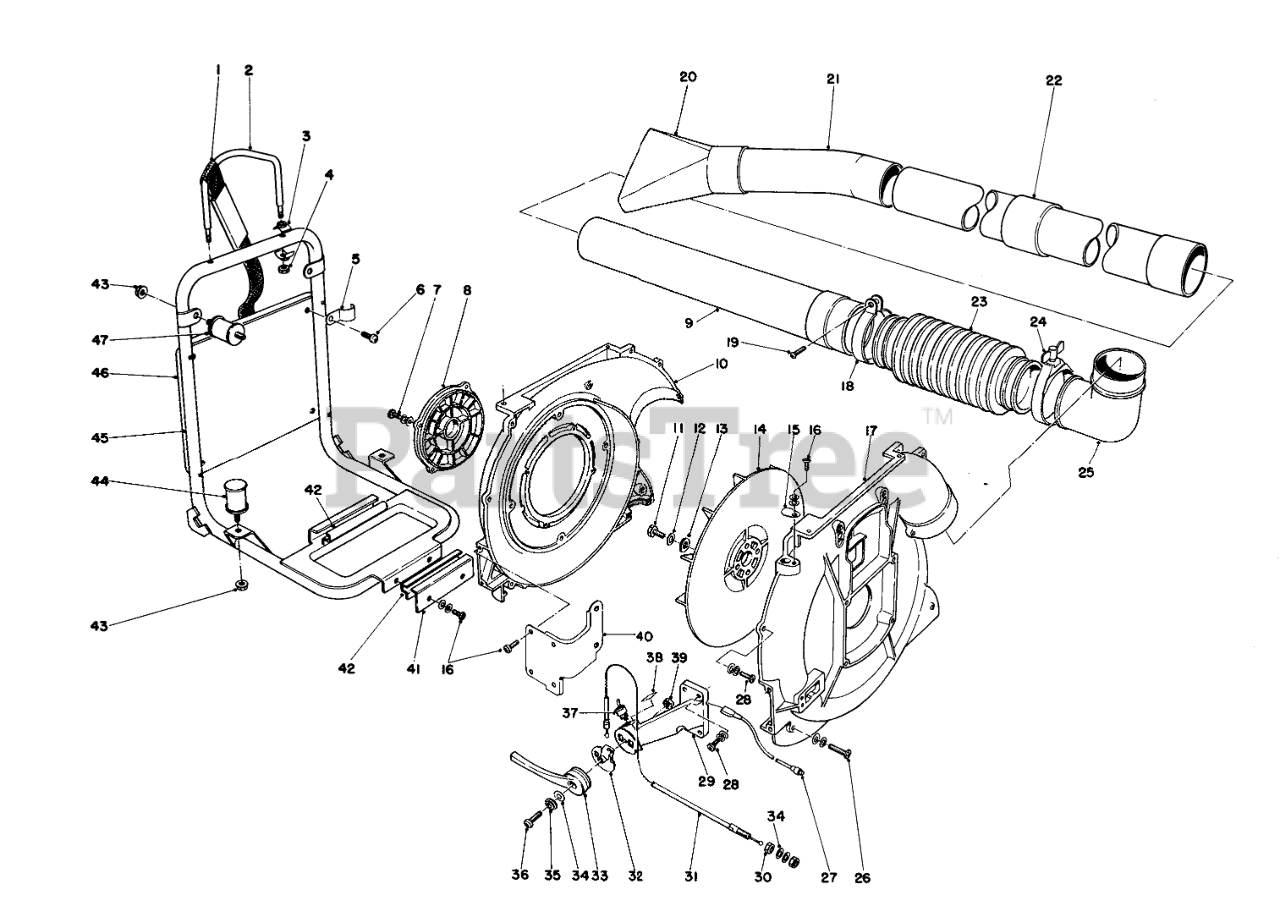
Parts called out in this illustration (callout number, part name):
1	Shoulder Strap
3	Adapter
4	Locknut
5	Bracket Cushion
6	SCREW-SHWH
7	Screw
8	Grid, Fan Case
9	STRAIGHT PIPE/SWIVEL
10	Fan Case, Operator Side
12	Lockwasher
13	WASHER
16	SCREW
17	Fan Case, Starter Side
18	Clamp
19	Screw
20	FAN HD NOZZLE
21	CURVED PIPE
22	Straight Pipe
23	FLEXIBLE PIPE
24	CLAMP
25	Elbow
27	Lead Switch
28	Screw
29	THROTTLE LEVER BRKT
31	THROTTLE CABLE
33	THROTTLE LEVER
34	Washer
35	Washer
36	SCREW
37	SWITCH
38	STOP SWITCH DECAL
40	Bracket
41	Bracket-Fuel Tank
42	Cushion-Fuel Tank
44	Cushion
45	Frame, Back Pack
46	Back Pack Pad
47	Cushion
